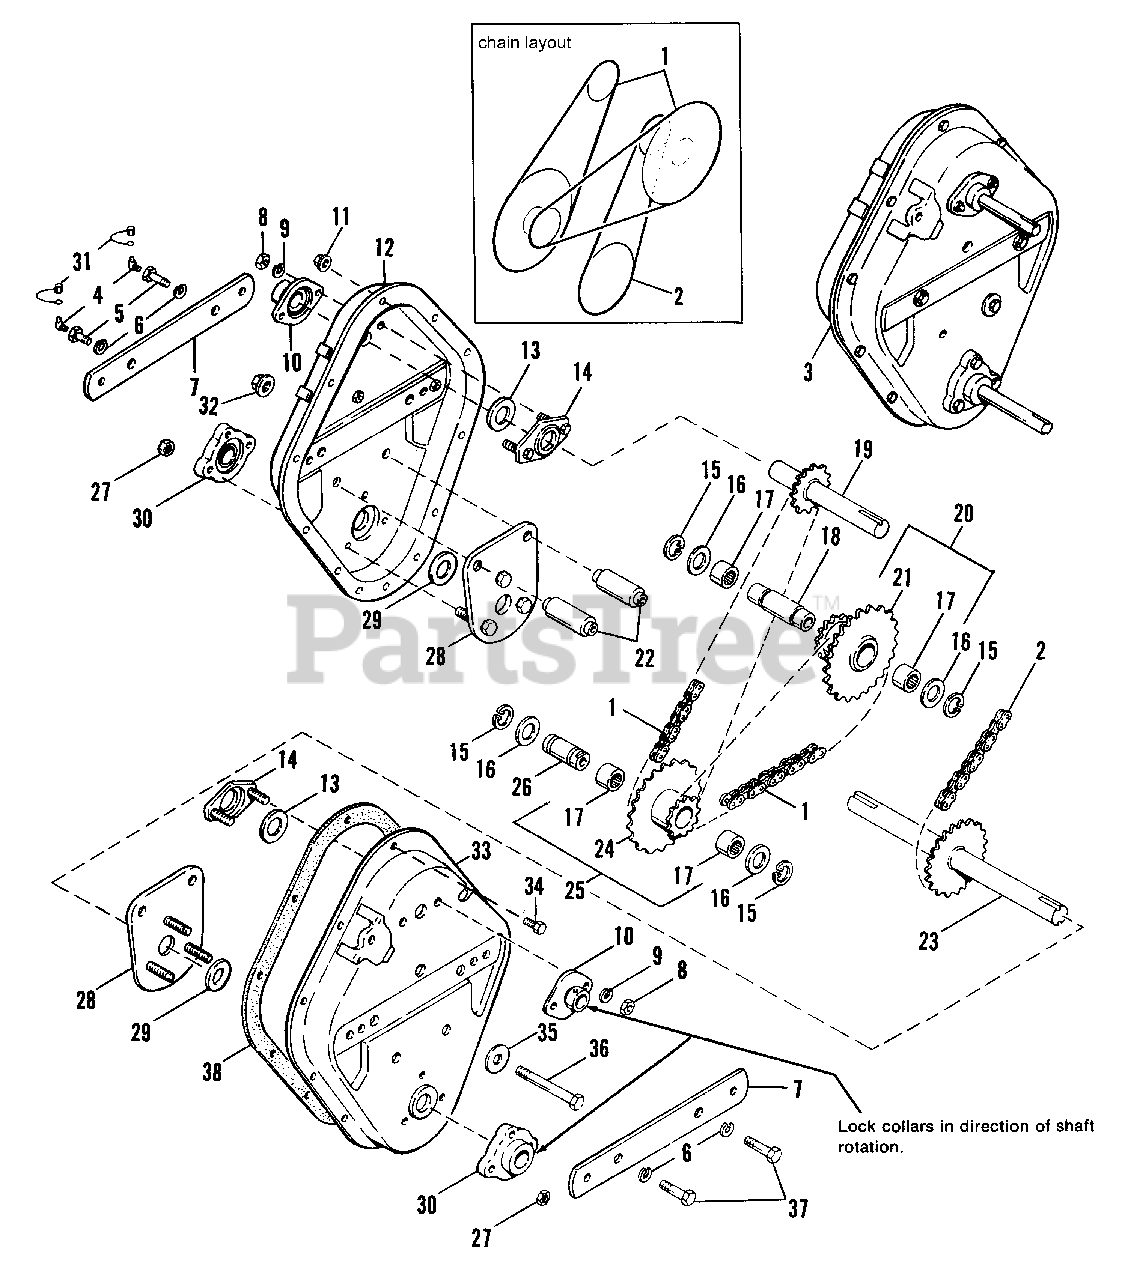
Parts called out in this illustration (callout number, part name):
3	TRANSMISSION SUB ASSY. (Incl. Ref. Nos. 1-16, 18-38 on this page & Ref. Nos. 1-5, 7, 11, 17, 18, 19, 34, 36 & 38 in the 36" Tiller-Drive Group)
4	FITTING, Grease
6	LOCKWASHER, 1/2
8	NUT, Hex, Full, 5/16-18
9	LOCKWASHER, 5/16
11	LOCKNUT, Hex, Full, 5/16-18
12	CASE ASSY, Half, R.H.
14	PLATE ASSY., Upper Bearing
15	RING, Retaining
17	BEARING, Roller
18	SPACER, Inter
19	SHAFT ASSY, Pulley
20	SPROCKET & BEARING ASSY.
22	SPACER
23	SHAFT ASSY., Tine
25	SPROCKET & BEARING ASSY.
26	SPACER, Inter.
27	LOCKNUT, Hex, Jam, 3/8-16
28	PLATE ASSY.
31	CAP, Grease
32	LOCKNUT, Flange, 1/2-13
33	CASE ASSY, Half, L.H.
34	CAPSCREW, Hex Hd., 5/16-18 x 5/8
35	WASHER, Plain, 1/2
36	CAPSCREW, Hex Hd., 1/2-13 x 4
37	CAPSCREW, Hex Hd., 1/2-20 x 1
